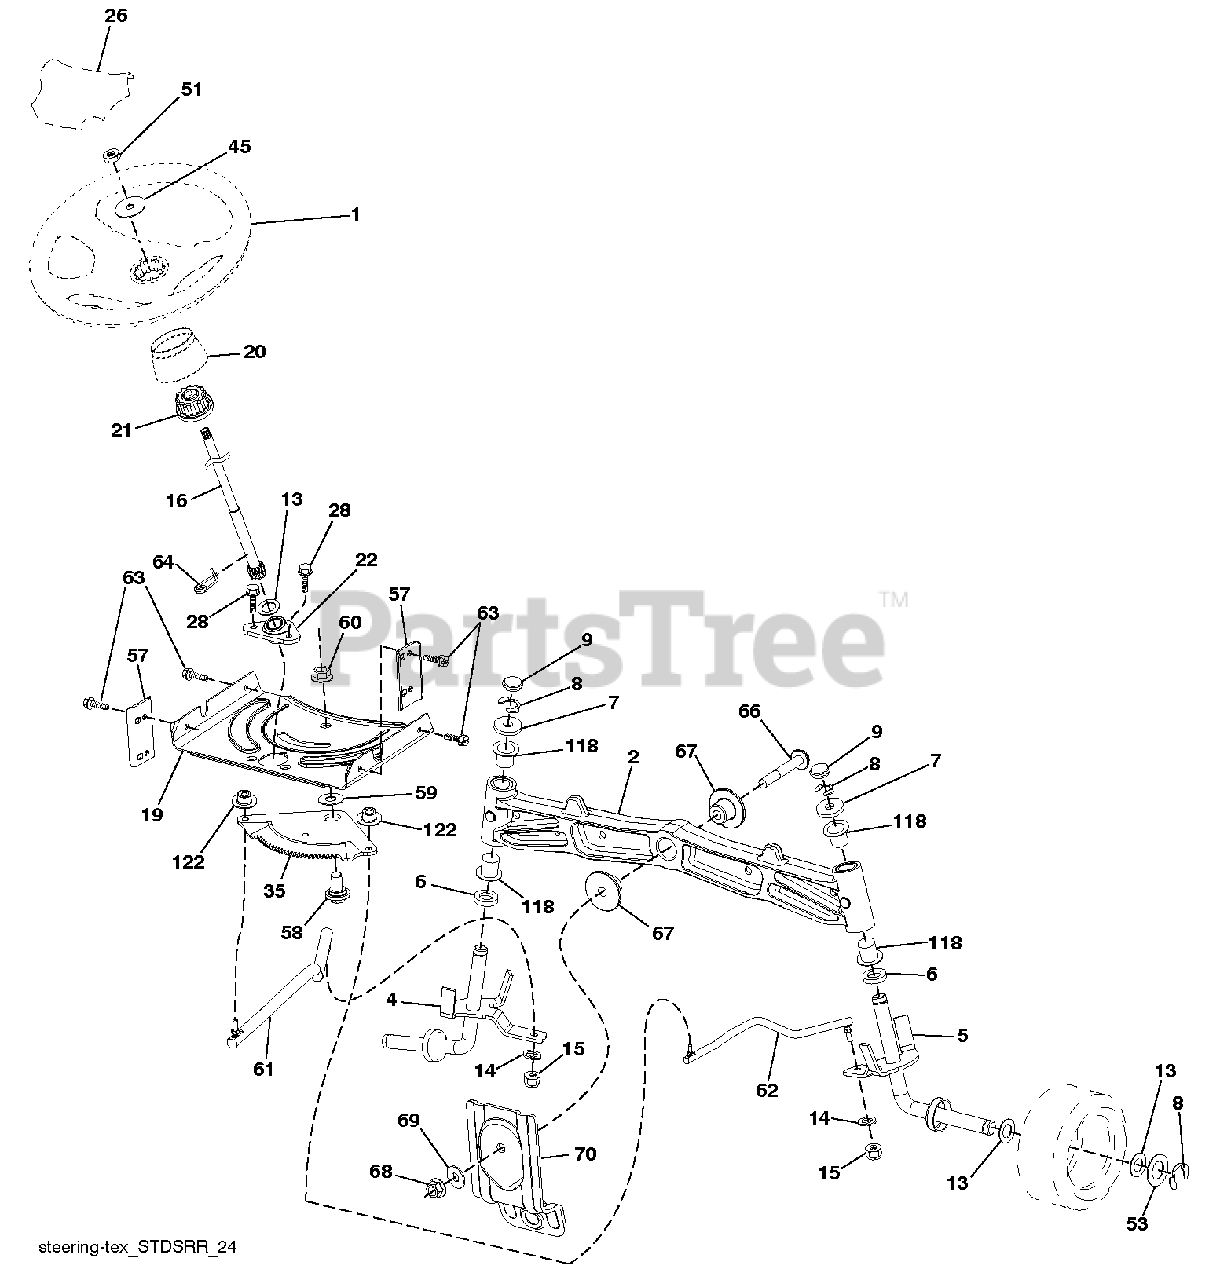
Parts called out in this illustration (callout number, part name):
1	WHEEL.STEERING.STDSRR.BLK/OV
2	AXLE.SVC.ASM CAST IRON.TEX
4	SPINDLE.WELDED.LH.16"TEX
5	SPINDLE.WELDED.RH.16"TEX
8	RING CLIP
9	CAP.SPINDLE
14	WASHER, LOCK 3/8
15	NUT CROWNLOCK 3/8-24
16	SHAFT.STEER.STEALTH.DD
19	PLATE.STEER.DDL.NLT/NG
21	ADAPTER, WHEEL STNG..
22	STEERING.SUPT.LOWER.
26	CAP.WHL.STRNG.STDSRRD.SRS.BLK
28	SCREW, 3/8-16X3/4
35	GEAR.SECTOR.PLATE.DDL.
45	WASHER 9/16"ID, 2 3/8"OD
51	NUT.HEX.1/2-20
53	WASHER.HARDENED
57	BRACKET.UPSTOP.TEX
58	BOLT.SHOULDER.SECTOR.P
59	WASHER.THURST.SECTOR.S
60	NUT FLANGE LOCK 5/8-11
61	DRAGLINK.LH.BALLSTUD.D
62	DRAGLINK.RH.BALLSTUD.D
63	SCREW
64	RETAINER.CLIP.SPRING.S
66	BOLT HEX FGHD 7/16-14 X 3 SERR
67	BUSHING.PM.FRONT AXLE
68	NUT.LOCK.FLANGE.7/16
69	WASHER.1.5X.505X.118
70	BRKT.DECK.SUSPENSION.F
118	BUSHING, AXLE CAST
